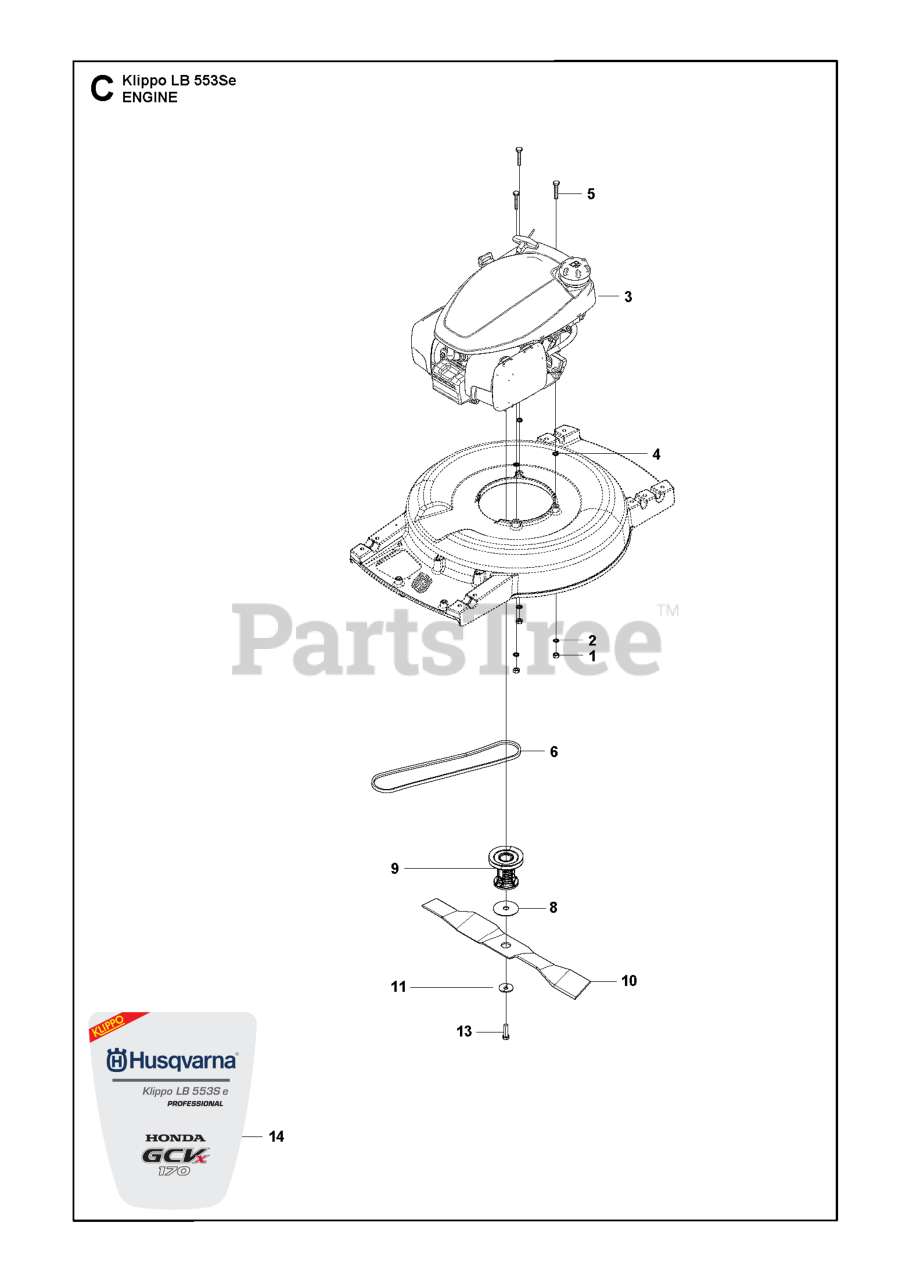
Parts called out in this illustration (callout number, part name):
1	LOCKNUT M8
2	WASHER BRB 8.4X17
6	BELT
